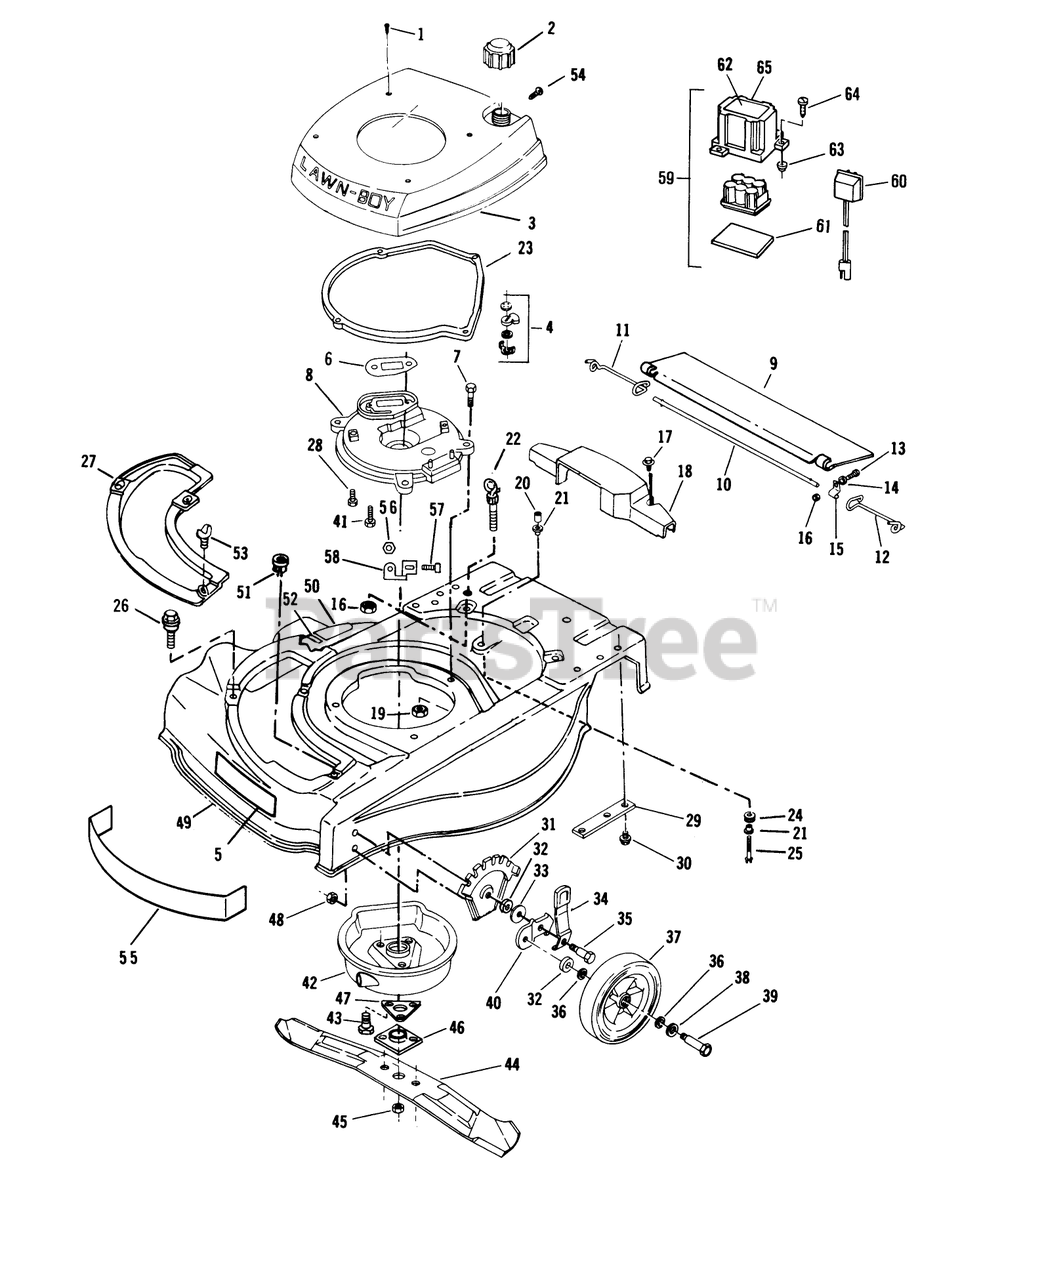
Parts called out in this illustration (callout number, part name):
1	SCREW LAWRENCE
2	FUEL CAP & INSERT
7	SCREW-HH
8	PLATE,MUFFLER F
10	ROD T/SHIELD ADV WIRE
11	SPRING;TRAILING SHIELD RH
12	SPRIG T/SHLD ASOC
14	Washer-Trailing Shield
15	CLAMP ROD KMC
16	LOCKNUT E
17	SCREW SEMS TRM HEX HD
19	NUT-LOCK F
20	SPACER
21	SPACER ECK PRES
22	BOLT-EYE
30	SCREW
31	PLATE HGT ADJ TRO
32	WASHER WROUGHT
33	WASHER
34	KNOB&SPRING FORMCO
35	BOLT
36	WASHER
37	WHEEL & TIRE KIT
38	SPACER
39	BOLT WHEEL
41	SCREW V
43	SCREW
45	NUT-BLADE
46	PLATE AND COLLAR ASM
47	SUPPORT F
48	LOCKNUT
53	WING SCREW LAWRE
54	SCREW S
56	LOCKNUT E
61	PAD-BATTERY
63	NUT-CLIP
64	SCREW - SELF TAPPING
